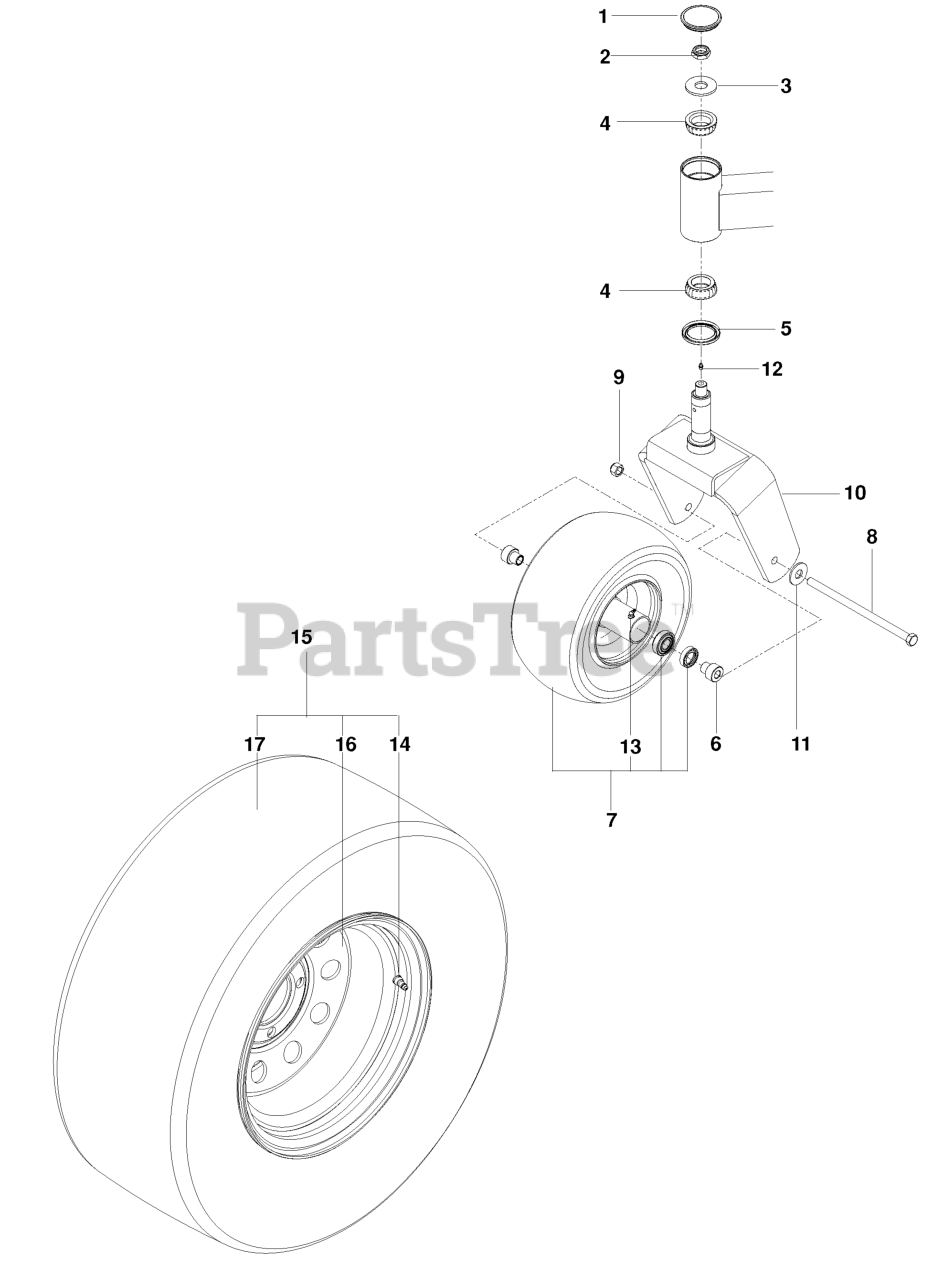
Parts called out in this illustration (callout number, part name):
2	NUT, 3/4-16 HEX THIN NYLOC ZD
3	WASHER, 3/4 HARDENED
4	BEARING W/CUP TAPPER ROLLER
5	SEAL, BEARING
6	AXLE SPACER
7	TIRE, 13 X 6.5-6 NO FLAT
8	HEX SCREW 1/2-13 X 9.5 GR5
9	NUT, 1/2-13 HEX FLG NYLOC ZD
10	FORK.CASTER.ORANGE
11	WASHER 1/2" FLAT
12	ZERK
13	ZERK
14	VALVE STEM TR-412
15	WHEEL, DRIVE, 26 X 12
16	RIM, 12 X 8.5, CENTERED
17	TIRE, 26-12 X 12
